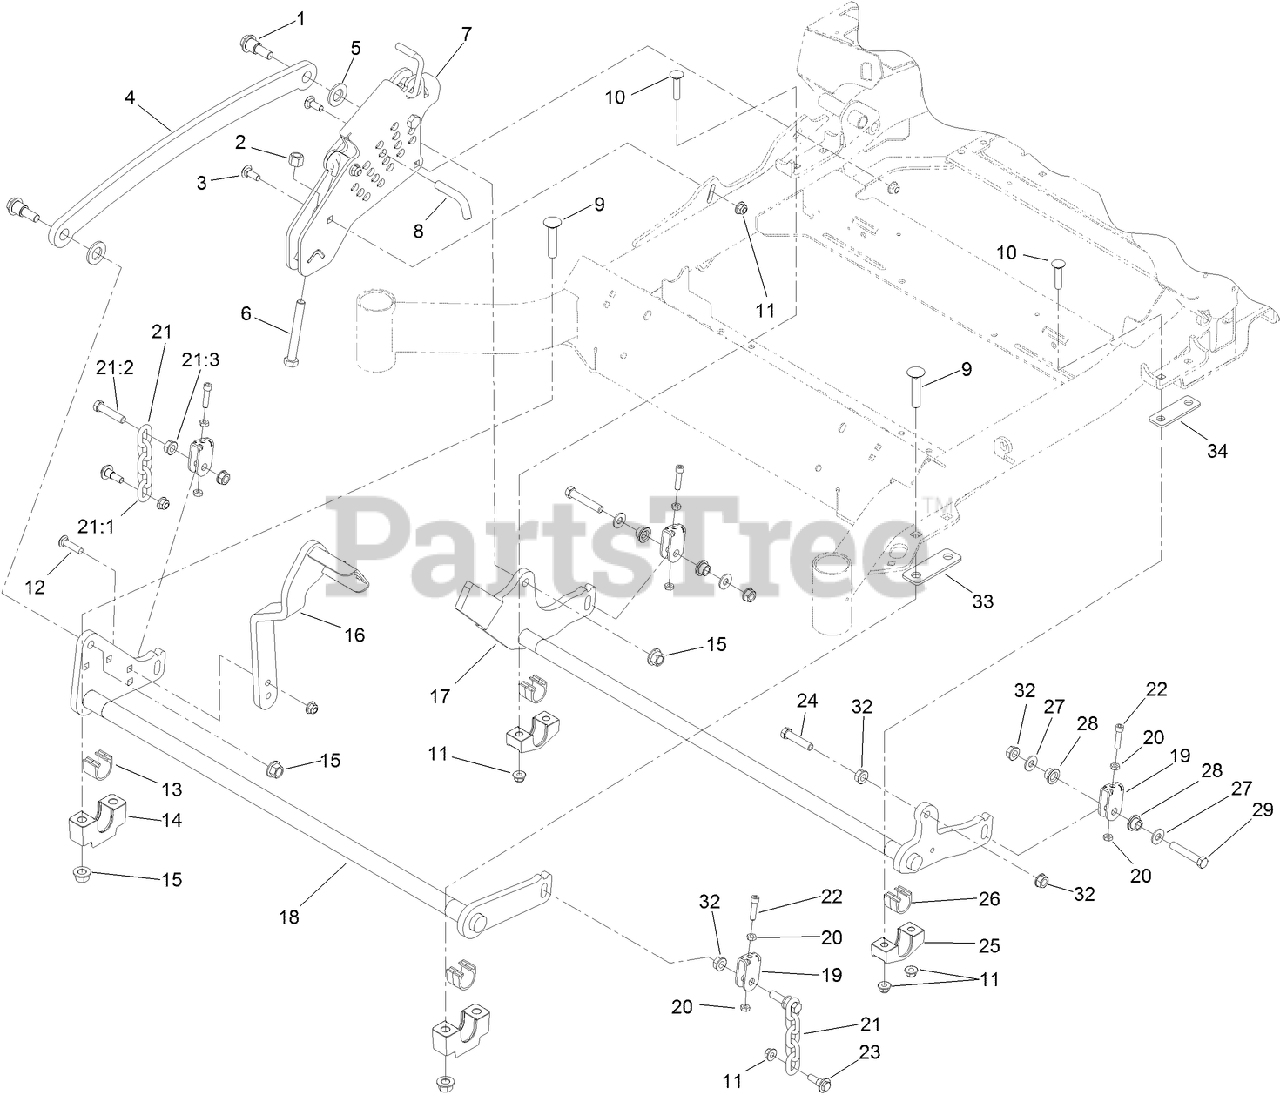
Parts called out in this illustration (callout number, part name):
1	SCREW-SHOULDER, HHF
2	NUT-LOCK, NI
3	BOLT-CARR
4	LINK-LIFT, DECK
5	WASHER-FLAT
6	BOLT-TAP
7	HOC ASM
8	PIN-HOC
9	BOLT-CARR
10	SCREW-CARR
11	NUT-HF, NI
12	SCREW-CARR
13	BEARING-CROSS SHAFT, FRONT
14	SUPPORT-CROSS SHAFT, BEARING
15	NUT-LOCK
16	LEVER-FOOT
17	LIFT-DECK, REAR
18	DECKLIFT-FRONT
19	YOKE-ADJUST, DECK
20	NUT-JAM
21	DECK LIFT CHAIN ASM
21:1	CHAIN-LIFT, DECK
21:2	SCREW-HH
21:3	NUT-HF
22	SCREW-HH
23	SCREW-SHOULDER, HHF
24	SCREW-HH
25	SUPPORT-CROSS SHAFT, BEARING REAR
26	BEARING-CROSS SHAFT, REAR
27	WASHER-FLAT
28	BUSHING-FLANGED
29	SCREW-HH
32	NUT-HF
33	SPACER-DECKLIFT, FRONT
34	SPACER-DECKLIFT, BACK
